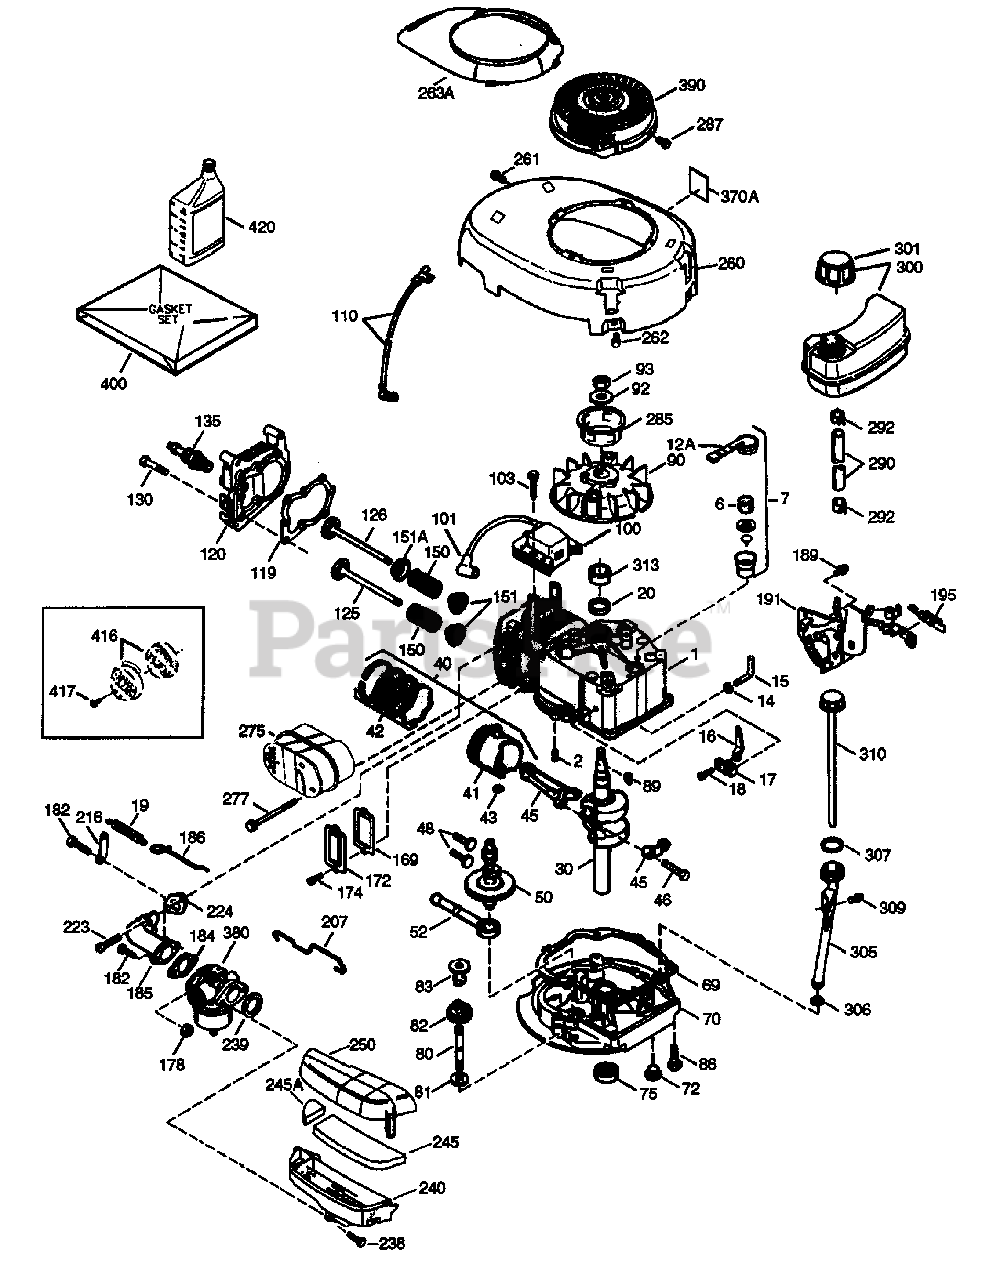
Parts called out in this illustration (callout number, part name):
1	Cylinder (Incl. 2 & 20)
2	Dowel Pin
6	Breather Element
7	Breather Body Ass'y. (Incl. 6 & 12A)
12A	Breather Cover & Tube (Incl. 12B)
15	Governor Rod (Incl. 14)
16	Governor Lever
17	Governor Lever Clamp
19	Extension Spring
20	Oil Seal
30	Crankshaft
40	Piston, Pin & Ring Set (Std.)
40	Piston, Pin & Ring Set (.010" OS)
40	Piston, Pin & Ring Set (.020" OS)
41	Piston & Pin Ass'y. (Std.)(Incl. 43)
41	Piston & Pin Ass'y. (.010" OS)(Incl. 43)
41	Piston & Pin Ass'y (.020" OS)(Incl. 43)
42	Ring Set (Std.)
42	Ring Set (.010" OS)
42	Ring Set (.020" OS)
43	Piston Pin Retaining Ring
45	Connecting Rod Ass'y. (Incl. 46)
46	Connecting Rod Bolt
48	Valve Lifter
50	Camshaft (MCR)
52	Oil Pump Ass'y.
69	Mounting Flange Gasket
70	Mounting Flange (Incl. 72 thru 83)
72	Oil Drain Plug
75	Oil Seal
80	Governor Shaft
82	Governor Gear Ass'y. (Incl. 81)
83	Governor Spool
89	Flywheel Key
90	Flywheel
92	Belleville Washer
93	Flywheel Nut
100	Solid State Ignition
101	Spark Plug Cover
103	Screw, Torx T-15,
110	Ground Wire
119	Cylinder Head Gasket
120	Cylinder Head
125	Exhaust Valve (Std.)(Incl. 151)
125	Exhaust Valve (1/32" OS)(Incl. 151)
126	Intake Valve (Std.)(Incl. 151)
126	Intake Valve (1/32" OS)(Incl. 151)
135	Resistor Spark Plug (RJ19LM)
150	Valve Spring
151	Valve Spring Cap
151A	Intake Valve Seal
169	Valve Cover Gasket
172	Valve Cover
178	Nut & Lock Washer
182	Screw
184	Carburetor To Intake Pipe Gasket
185	Intake Pipe
186	Governor Link
191	S.E. Brake Bracket (Incl. 195)
195	Terminal
207	Throttle Link
216	R.P.M. Adjusting Lever
224	Intake Pipe Gasket
239	Air Cleaner Gasket
240	Air Cleaner Body
245	Air Cleaner Filter
245A	Air Cleaner Filter
250	Air Cleaner Cover
260	Blower Housing
263A	Starter Grill
275	Muffler
285	Starter Cup
290	Fuel Line
292	Fuel Line Clamp
300	Fuel Tank (Incl. 292 & 301)
301	Fuel Cap
305	Oil Fill Tube
306	"O"-Ring
307	"O"-Ring
310	Dipstick
370A	Lubrication Decal
380	Carburetor (Incl. 184)
390	Rewind Starter (NOTE: This engine could have been built with 590737 starter.
400	Gasket Set (Incl. Items Marked PK in Notes) Incl. part #'s 26756 (1), 28833 (1) 34338 (1), 35261 (1), 36783 (1), 36786 (1) 36832 (1), 37128 (1).
416	Spark Arrestor Kit (Incl. 417) (Optional)
417	Screw (Optional)
420	SAE 30 4-Cycle Engine Oil (Quart)
